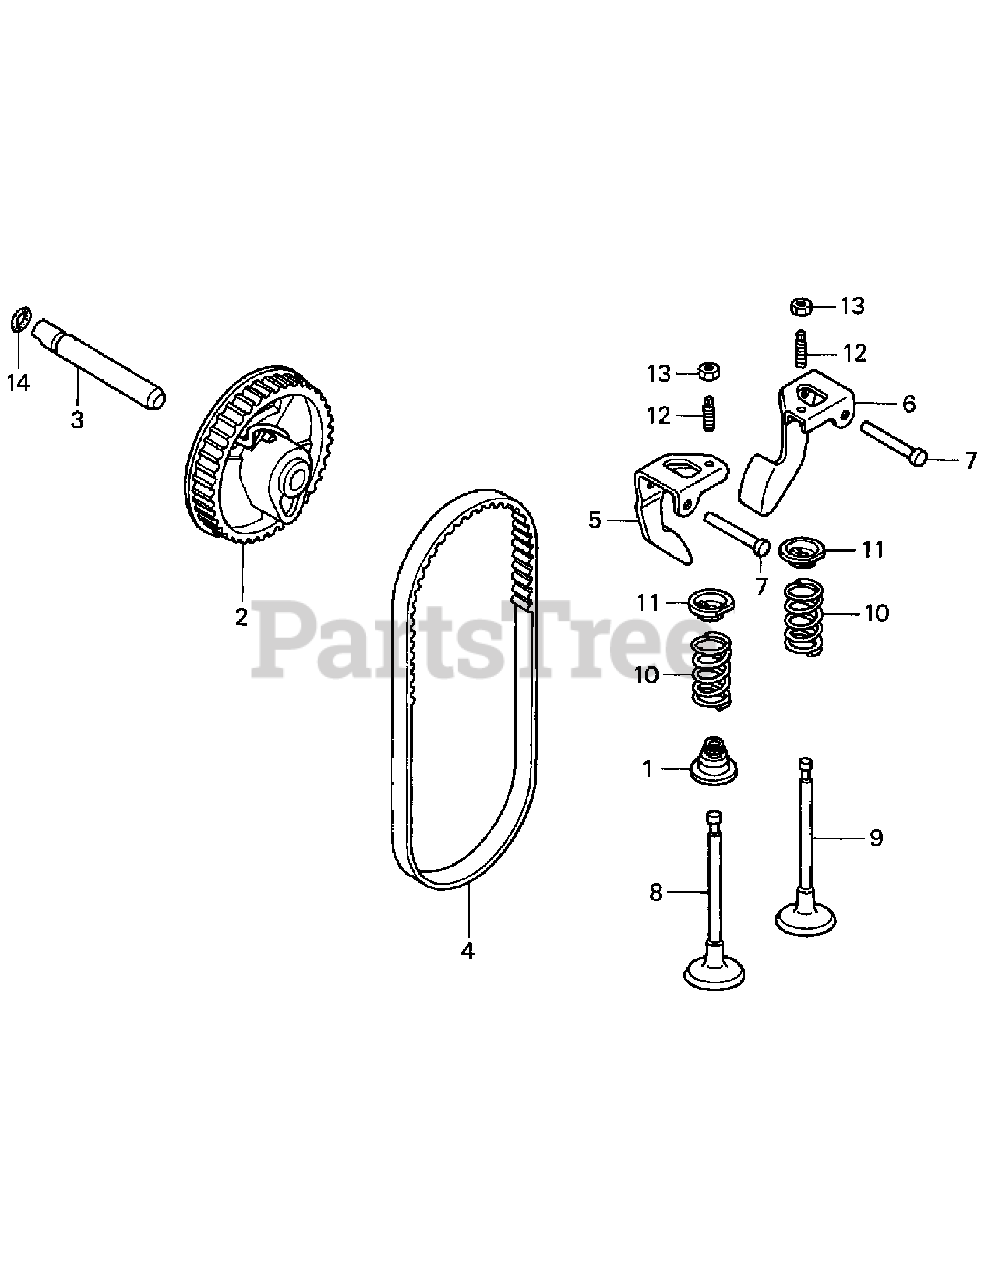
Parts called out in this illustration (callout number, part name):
1	Seal, Valve Stem
2	Pulley Comp., Camshaft
3	Shaft, Cam Pulley
4	Belt, Timing (84Hu7 G-200)
5	Arm, In. Valve Rocker
6	Arm, Ex. Valve Rocker
7	Shaft, Rocker Arm
8	Valve, In.
9	Valve, Ex.
10	Spring, Valve
11	Retainer, Valve Spring
12	Screw, Tappet Adjusting
13	Nut, Tappet Adjusting
14	O-Ring, 6.8X1.9
